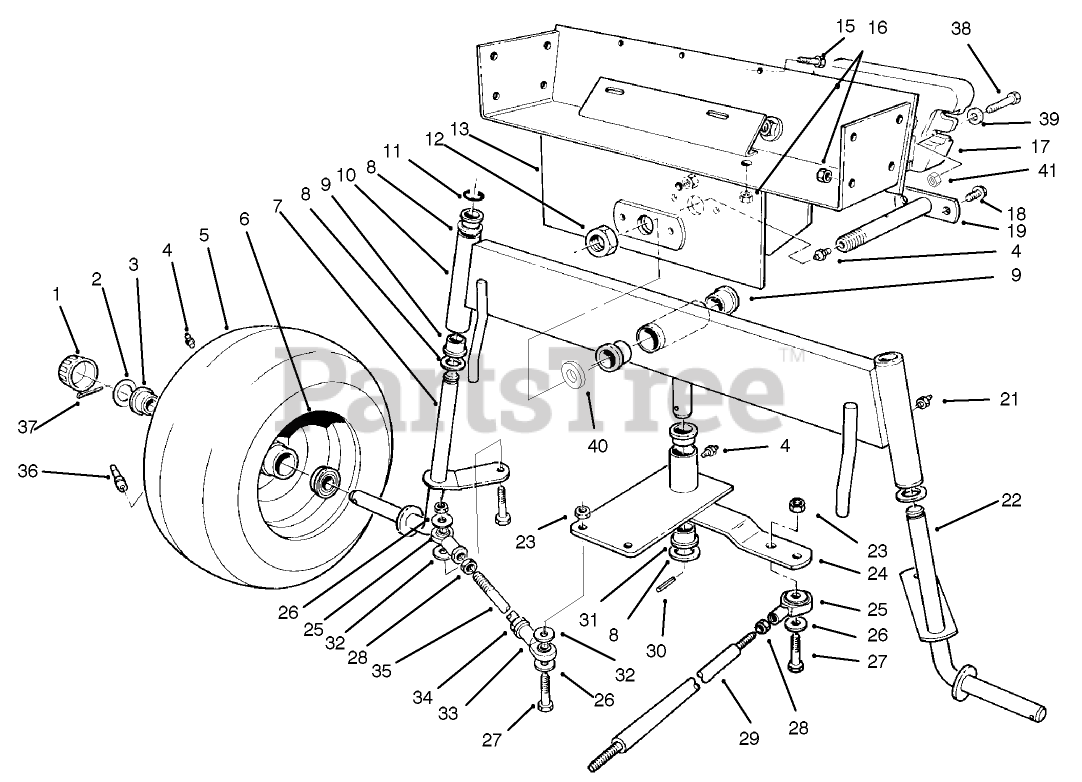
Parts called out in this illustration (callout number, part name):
1	CAP-HUB
2	WASHER-PLAIN
3	Bearing
4	FITTING-GREASE
6	FRONT WHEEL
7	Spindle R.H.
8	WASHER-THRUST
9	BUSHING PM
10	Axle-Rear (Incl. Ref. #9 & 20)
11	E-RING
12	NUT-LOCK NI
13	Frame-Rear
15	SCREW-HH
16	NUT-LOCK, NI
17	WEIGHT-REAR
18	SCREW-HHFTF
19	Axle-Pivot
21	GREASE FITTING
22	Spindle LH.
23	NUT-LOCK, NI
24	Plate-Pivot (Incl. Ref. #4 & 30)
25	BALL JOINT RH
26	WASHER-FLAT
27	SCREW-HH
28	NUT-JAM
29	Rod-Steering
30	PIN-ROLL
31	BEARING-FLANGE
32	WASHER
33	BALL JOINT LH
35	TIE ROD - STEERING
36	STEM-VALVE
37	PIN-COTTER
38	SCREW-HH
39	WASHER-FLAT
40	WASHER-FLAT
41	NUT-HH
